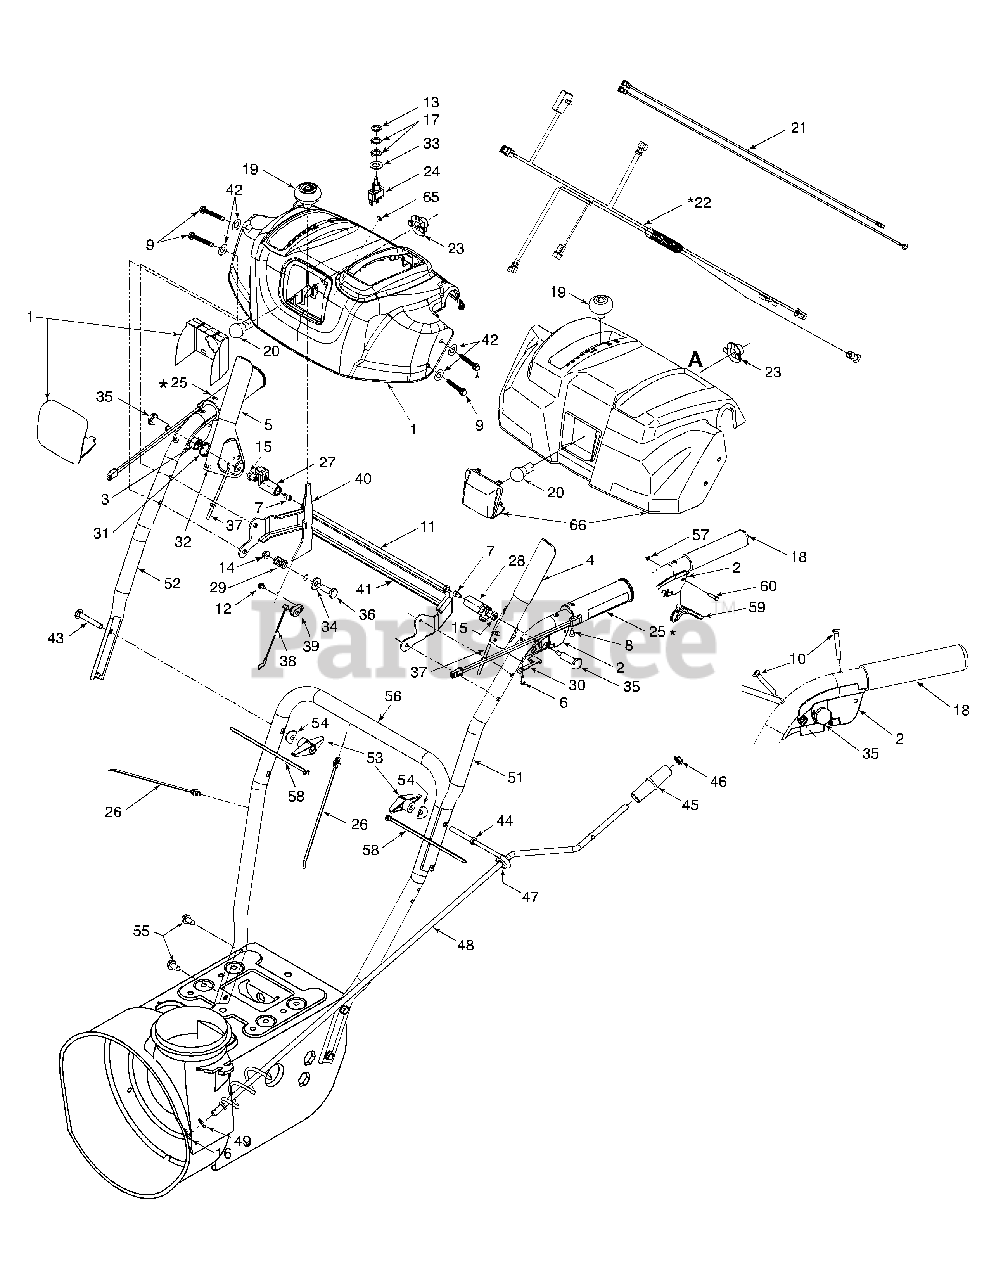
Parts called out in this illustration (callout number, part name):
1	Handle Panel Ass’y - Yellow
2	LH Clutch Lock Handle Ass’y
3	RH Clutch Lock Handle Ass’y
4	EngagementHandle Assembly LH
5	Engagement Handle Assembly RH
6	Screw #8-16 x .50
7	Screw 1/4-20 x .375
8	Oval HD C-Sunk Scr #10 x 5/8
9	Hex TT-Tap Scr 1/4-20 x 1.75
10	Oval C-Sunk Hd Screw 10-24 x 1.375
11	Pivot Rod
12	Screw #10-16 x .50
13	Hex Nut
14	Hex L-Flanged Nut 1/4-20 Gr. F Nylon
15	Hex Shoulder Nut 1/4-20
16	Int. Cotter Pin .072 x 1.13" Lg.
17	Lock Ring - Toggle Switch
19	Shift Knob
19	Shift Knob - Yellow
20	Lamp #1295
21	Wire Harness
22	Heated Grip Wire Harness
23	Socket
24	Toggle Switch - Single Throw
25	Heated Grip
26	Cable Tie 19 x 8.39"
27	Lock Plate
28	Clutch Lock Cam
29	Compression Spring .38 ID x .88 Lg
30	Spring: Clutch Lock
31	Torsion Spring .8156 x .3038
32	Rubber Bumper
33	Flat Washer .469 ID x .88 OD x .063
34	Flat Washer .38 ID x .87 OD x .09
35	Shoulder Screw 1/4-20 x 1.345
36	Shoulder Screw .374 Dia. x 1.05 Lg.
37	Z Fitting
38	SelectorSpeedCable
39	Cable Barrel Holder
44	Chute Crank Eye Bolt Special
45	Knob 1.0 x 3.2
46	Push Nut 3/8" Rod
47	Grommet
49	Flat Washer .406" I.D. x .75" O.D.
53	Handle Knob Assembly
54	Saddle Wash. .320 ID x .937 OD
55	Hex Wash HD Lo Tap Scr 5/16 x .75
57	E Ring
58	Cable Tie
59	SteeringControl
60	Pin 3/16
65	E-Ring 0.76
66	Handle Panel Ass’y - Troy-Bilt
